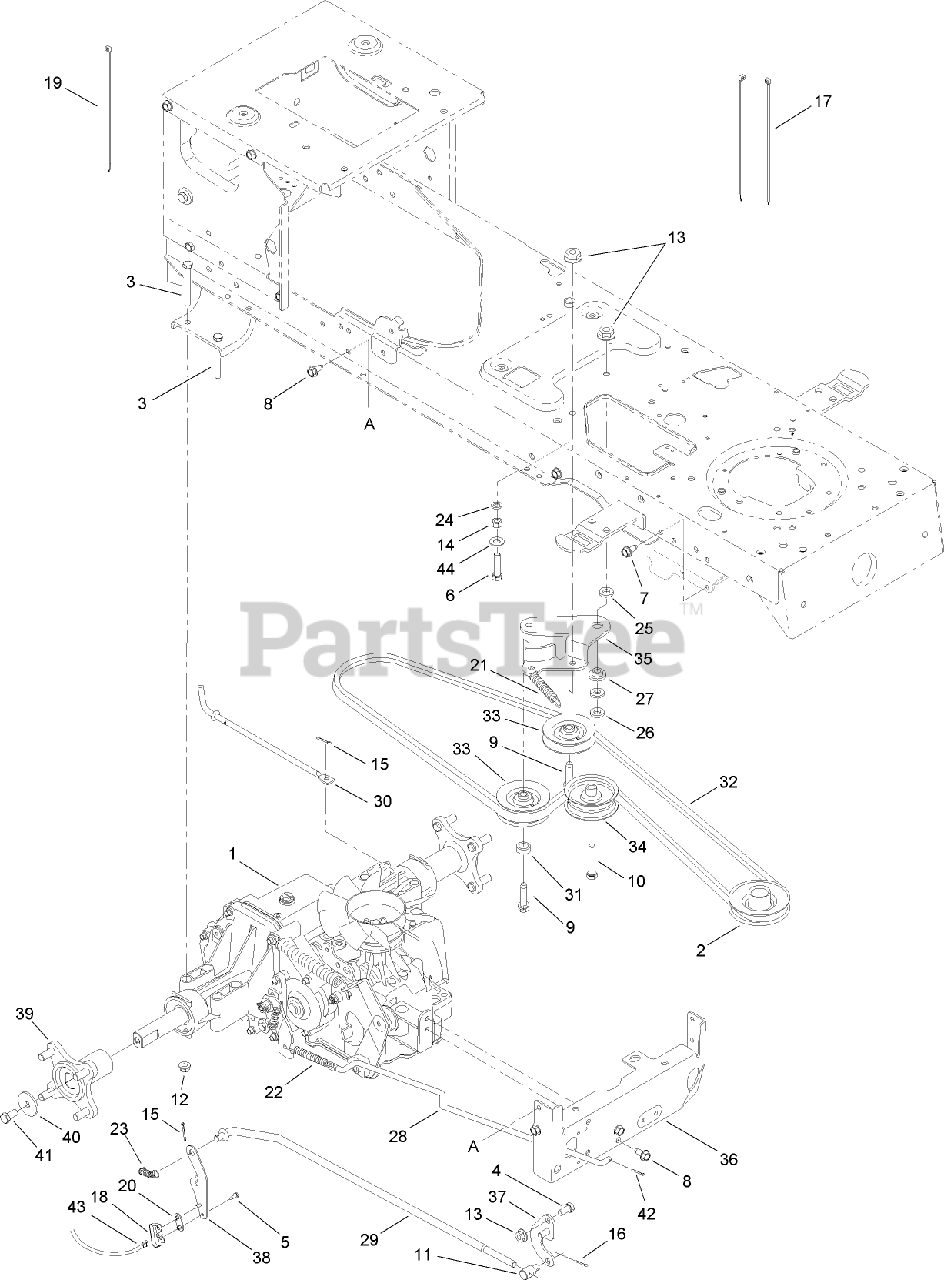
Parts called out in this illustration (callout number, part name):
1	TRANSMISSION ASM
2	PULLEY-ENGINE
3	SCREW-HEX
4	SCREW-HH
5	SCREW-HWHTF
6	SCREW-HH
7	SCREW-HWHTF
8	SCREW-HH, TAP
9	SCREW-TAP
11	FERRULE
12	NUT-LOCK, FLANGE
13	NUT-LOCK, FLANGE
14	NUT-HEX
15	PIN-COTTER
16	PIN-COTTER
17	TIE-CABLE
18	SWITCH-SPRING, SHORT
19	TIE-CABLE
20	PLATE-INSULATOR
21	SPRING-EXTENSION
22	SPRING-EXTENSION
23	SPRING-EXTENSION
24	WASHER-LOCK
25	WASHER-FLAT
26	WASHER-FLAT
27	SPACER-SHOULDER
28	ROD-BRAKE
29	ROD-CONTROL
30	ROD-DISENGAGE, HYDRO
31	SPACER
34	PULLEY-IDLER, FLAT
35	BRACKET-IDLER, CENTER DOUBLE
36	BRACKET-TRANSMISSION
37	BRACKET-CONTROL
38	BRACKET-ACTUATOR
39	WHEEL HUB ASM
40	WASHER-FLAT
41	SCREW-HH
42	PIN-COTTER
44	WASHER-FLAT
